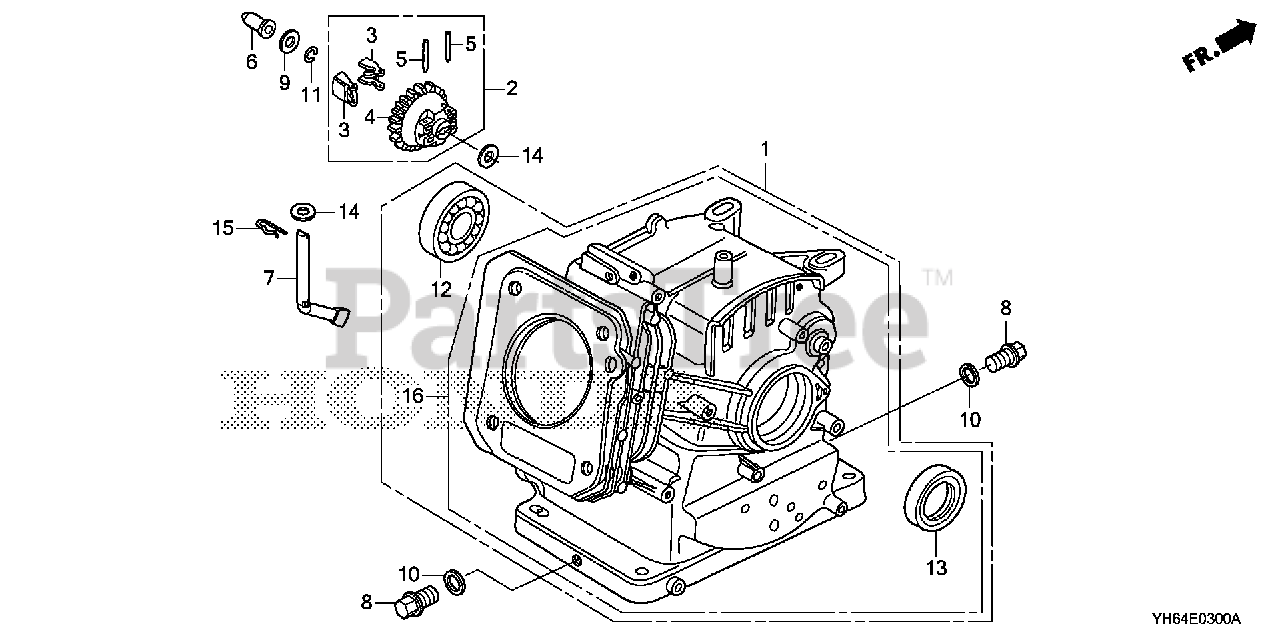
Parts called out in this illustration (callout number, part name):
1	CYLINDER ASSY.
2	GOVERNOR ASSY.
3	WEIGHT, GOVERNOR
4	HOLDER, GOVERNOR WEIGHT
5	PIN, GOVERNOR WEIGHT
6	SLIDER, GOVERNOR
7	SHAFT, GOVERNOR ARM
8	BOLT, DRAIN PLUG
9	WASHER, THRUST (6MM)
10	WASHER, DRAIN PLUG (10.2MM)
11	CLIP, GOVERNOR HOLDER
12	BEARING, RADIAL BALL (62/22)
13	OIL SEAL (22X35X6)
14	WASHER, PLAIN (6MM)
15	PIN, LOCK (8MM)
